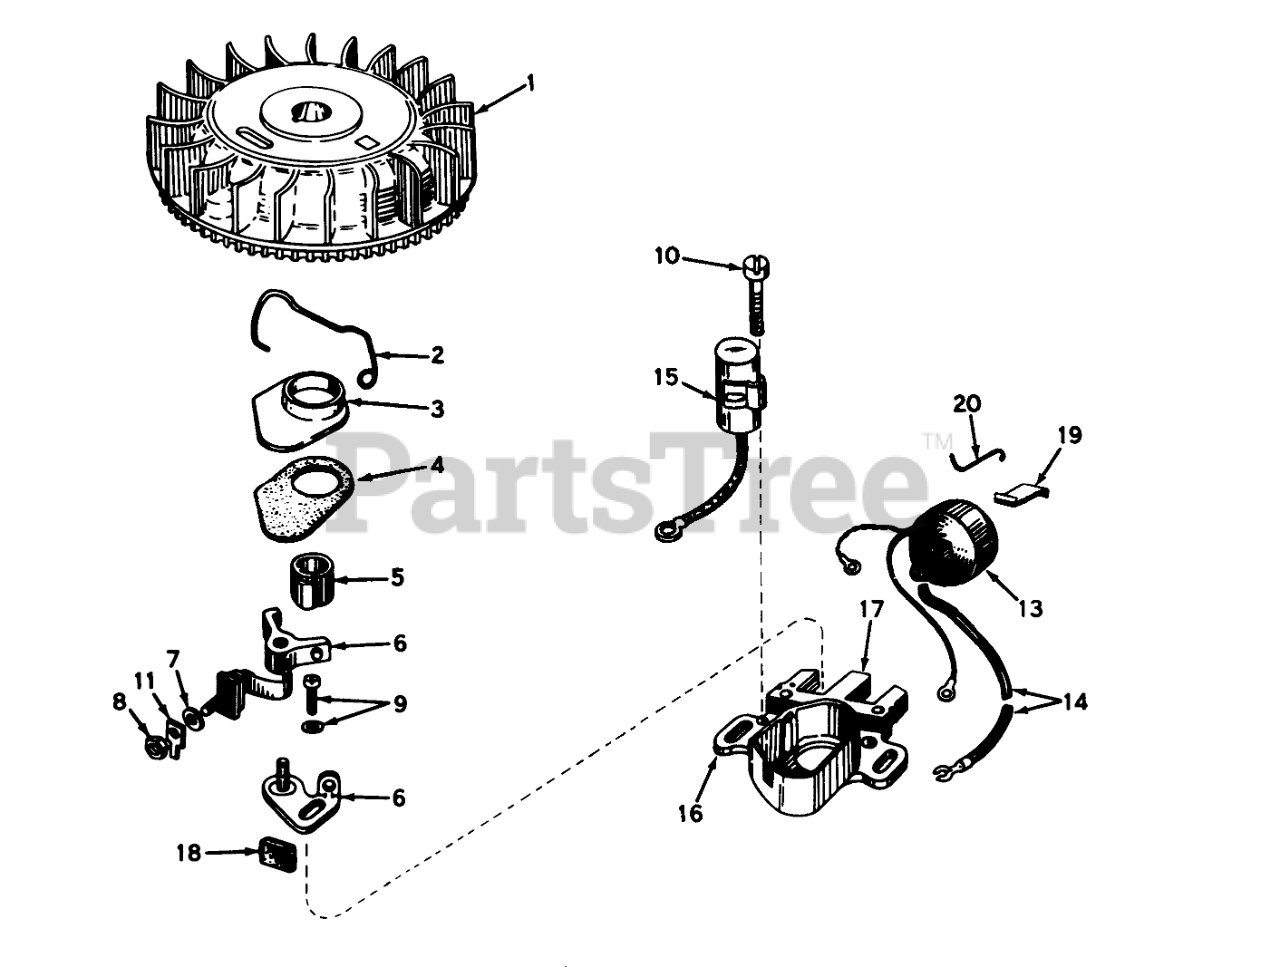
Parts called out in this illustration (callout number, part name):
1	FIywheel
2	Spring Breaker Box
3	Cover, Dust
4	Gasket Dust Cover
5	Cam, Breaker
6	Breaker Assy.
7	Washer
8	DECAL
9	Breaker Screw
10	Condenser Screw
11	Terminal, Ground
13	Coil Assembly (Incl. No. 14)
14	Wire, Lead
15	Condenser
16	Core & Plate
17	Stator Assembly (Incl. Nos. 2, 3, 4, 6 thru 16, 18, 19 & 20
18	Felt,Cam Wiper
19	Spring Coil Wedge
20	Clip, Coil
